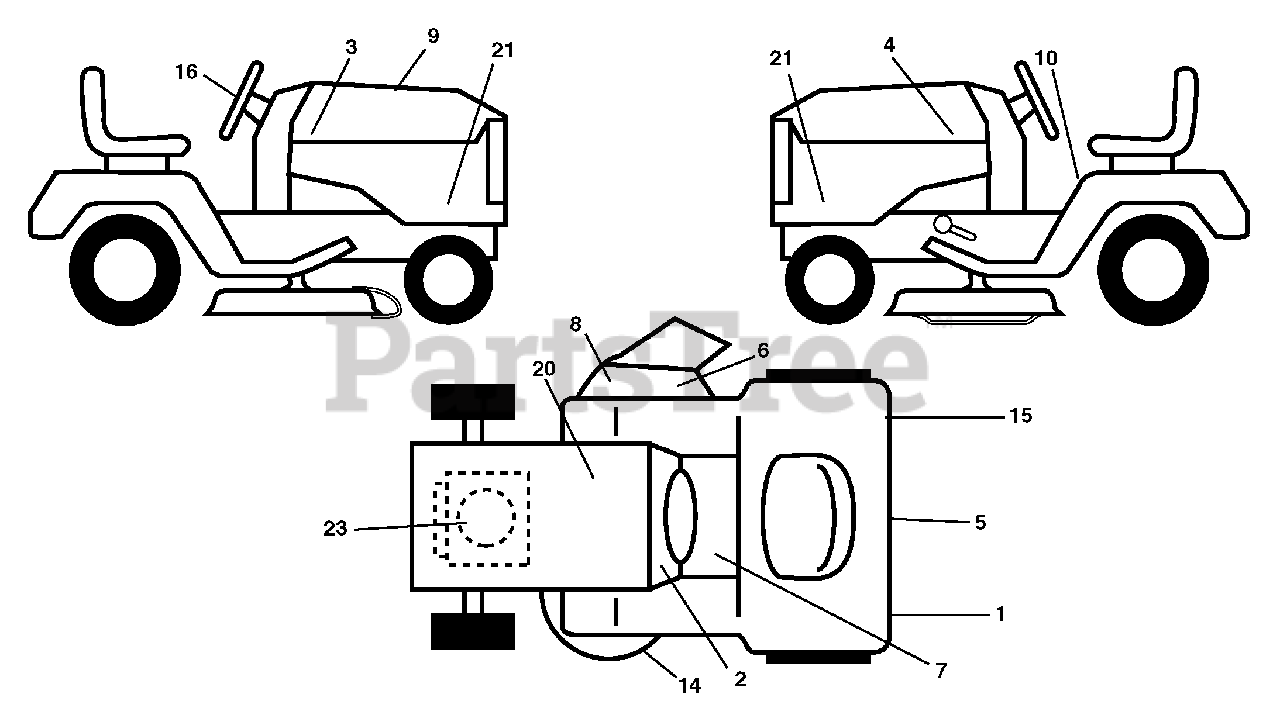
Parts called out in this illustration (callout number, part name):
1	Refl ector, LH
2	Decal Dash
3	Decal Hood Rh
4	Decal Hood LH
5	Decal Fender Logo
6	Decal Warning, Keep Hand Away
7	Decal Oper. Cruise Control
8	Decal Deck "B" 42"
9	Decal Replacement Hood
10	Decal Fender Danger
14	Decal V-Belt Schematic
15	Decal Refl ector, RH
16	Decal Ins Strg Whl
20	Decal Battery
21	Decal Side Panel Logo
23	Decal Engine
